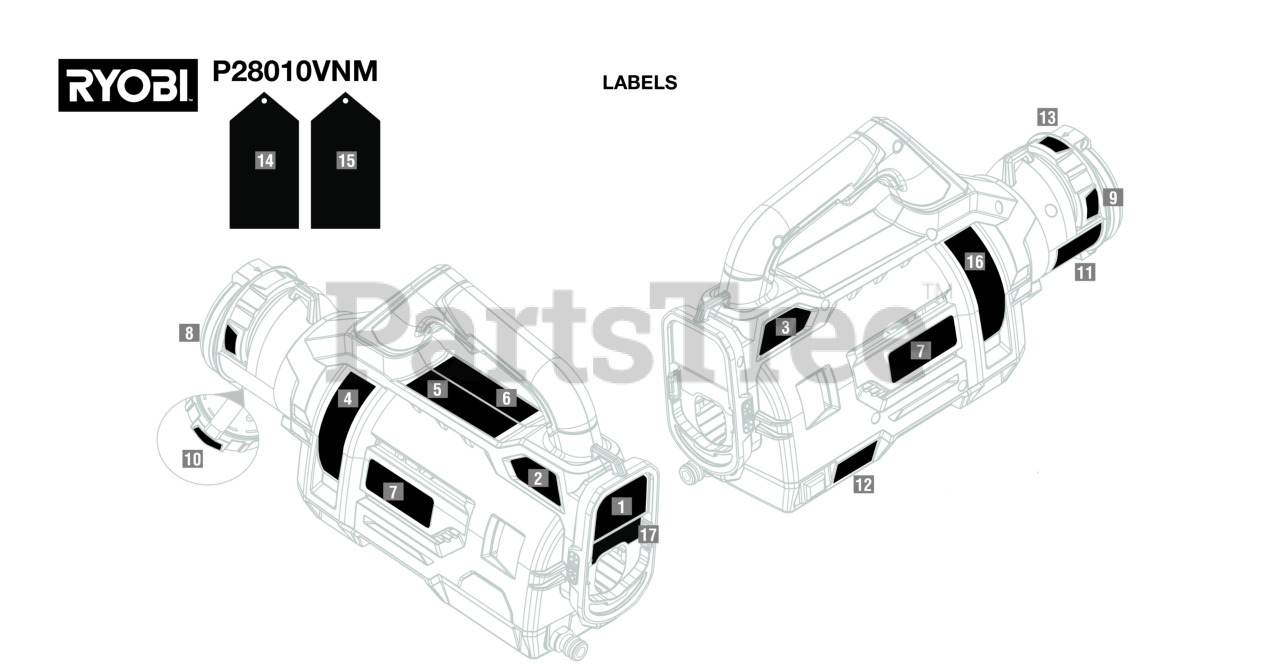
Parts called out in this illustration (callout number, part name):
1	Data Label (Foot)
2	18V Label (Left)
3	18V Label (Right)
4	Electrostatic Logo Label (Left)
5	Warning/Icon Label
6	Warning Label
7	Logo Label
8	High Spray Nozzle Label
9	Low Spray Nozzle Label
10	Medium Spray Nozzle Label
11	Caution Label
12	ES On/Off Label
13	Remove/Eject Puck Label
14	Cleaning Nozzle Reference Guide Hang Tag (EN/FR/SP)
15	Cleaning Nozzle Reference Guide Hang Tag (PORT)
16	Electrostatic Logo Label (Right)
17	Clean Tank and Lines Label
